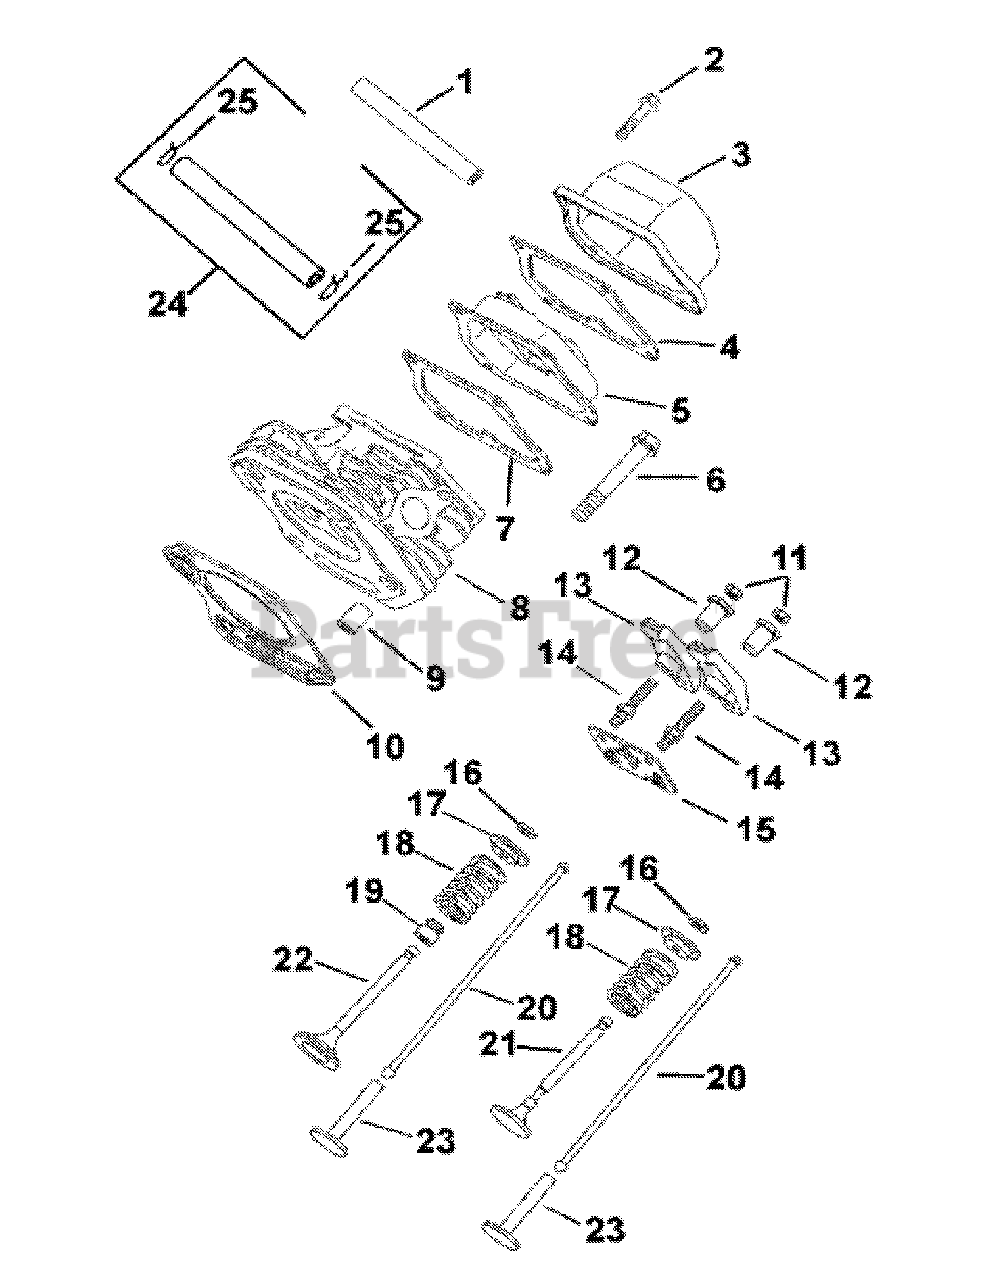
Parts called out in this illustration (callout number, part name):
1	Breather Hose
4	Valve Cover Gasket
5	Breather Assy.
6	Cylinder Head Screw
7	Breather Gasket
8	Cylinder Head
10	Cylinder Head Gasket
12	Rocker Arm Pivot
14	Valve Adjusting Screw
17	Valve Spring Cap
19	Valve Stem Seal
21	Exhaust Valve
